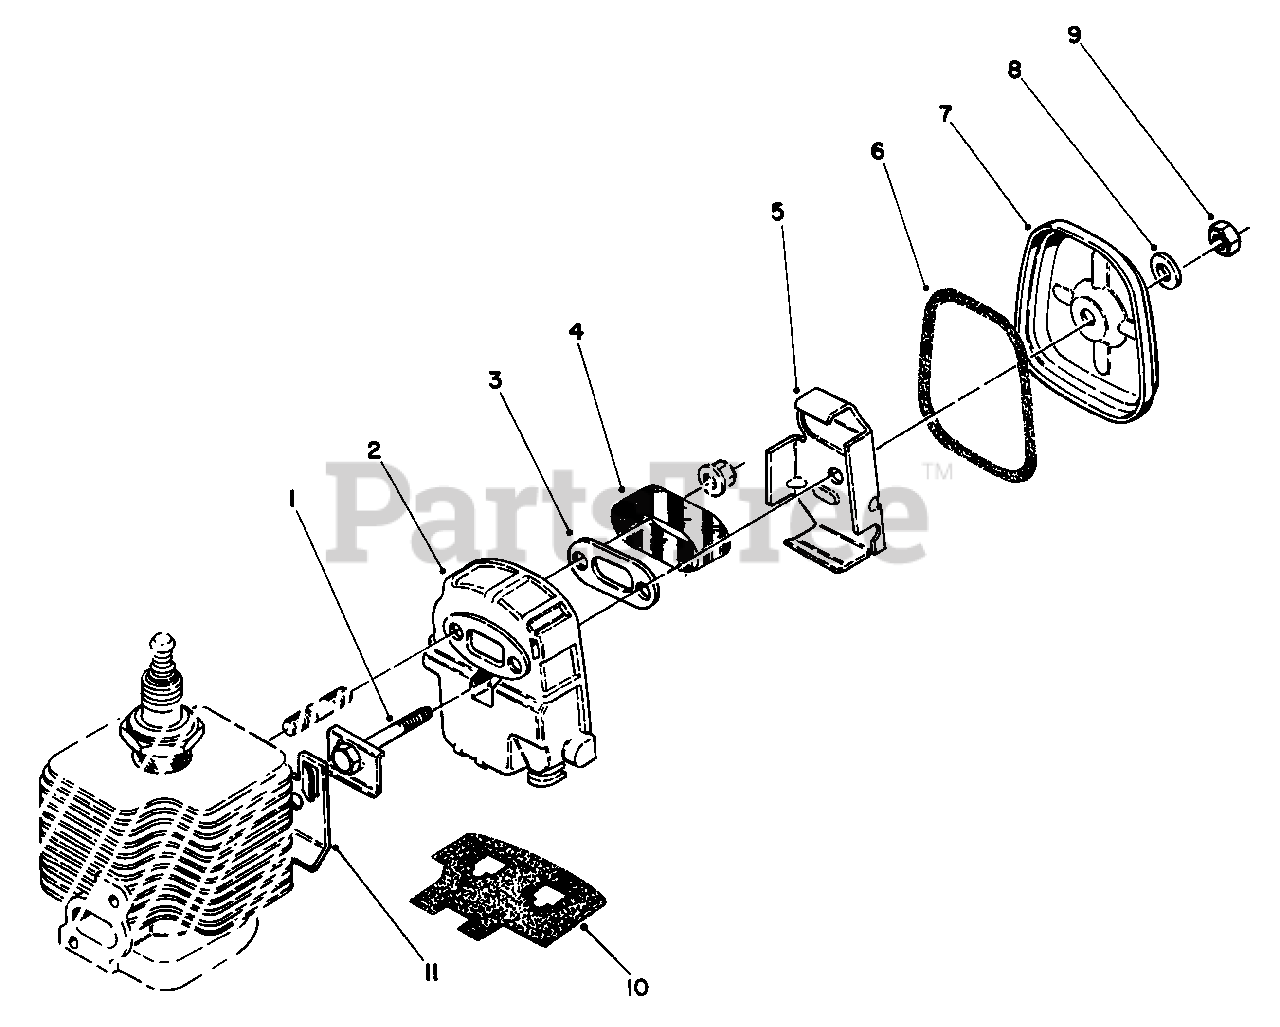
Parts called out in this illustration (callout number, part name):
1	Bolt-Muffler Body
2	Body-Muffler
6	Gasket-Muffler Seal
7	Lid-Muffler
8	Washer-Gasket
11	Gasket-Muffler
